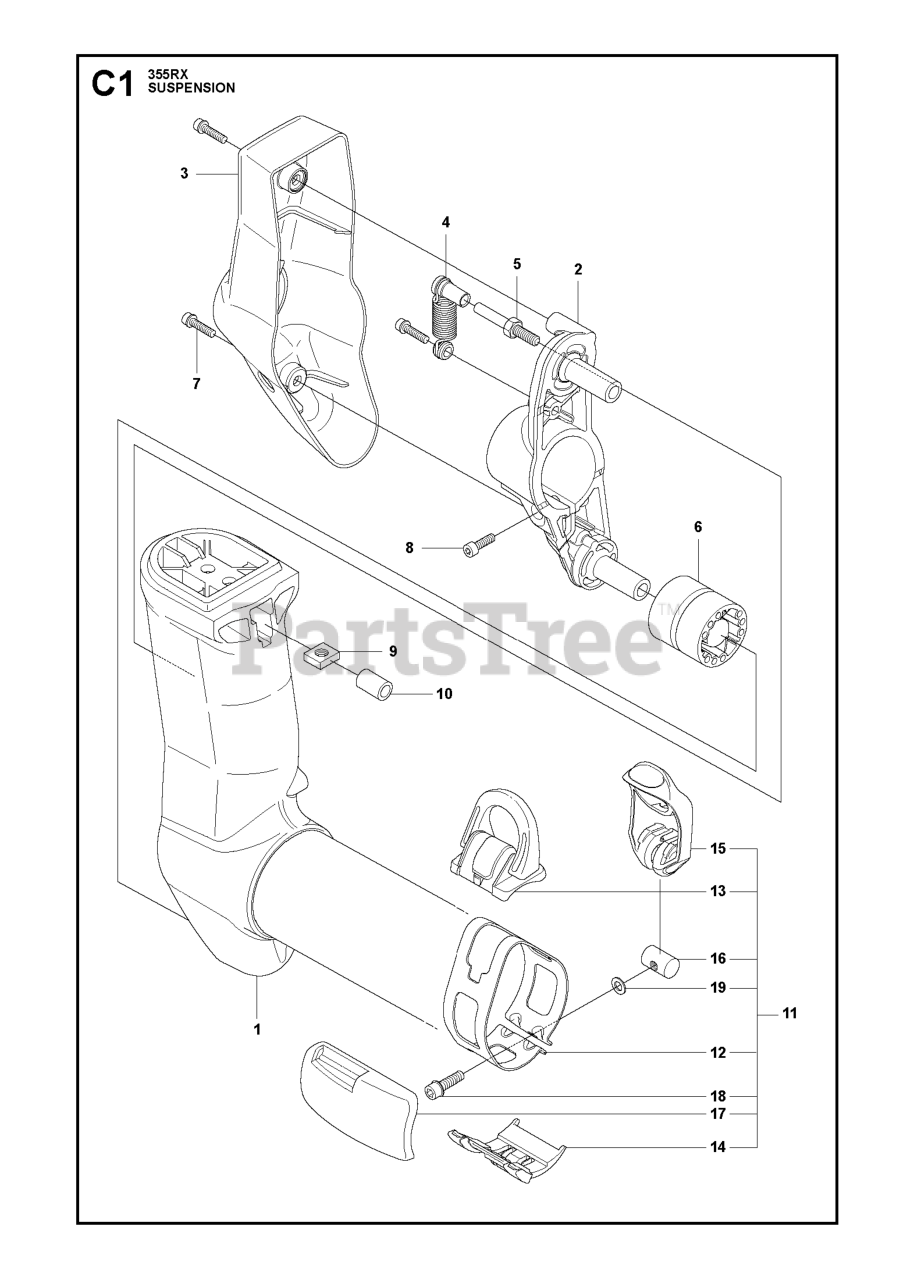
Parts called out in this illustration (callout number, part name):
1	SUSPENSION
5	PARALLEL PIN
6	ANTIVIBE ELEMENT
7	SCREW IHSCFM
11	LOOP
14	GUIDE RAIL
17	WEAR PROTECTION
19	WASHER 5.3X12
